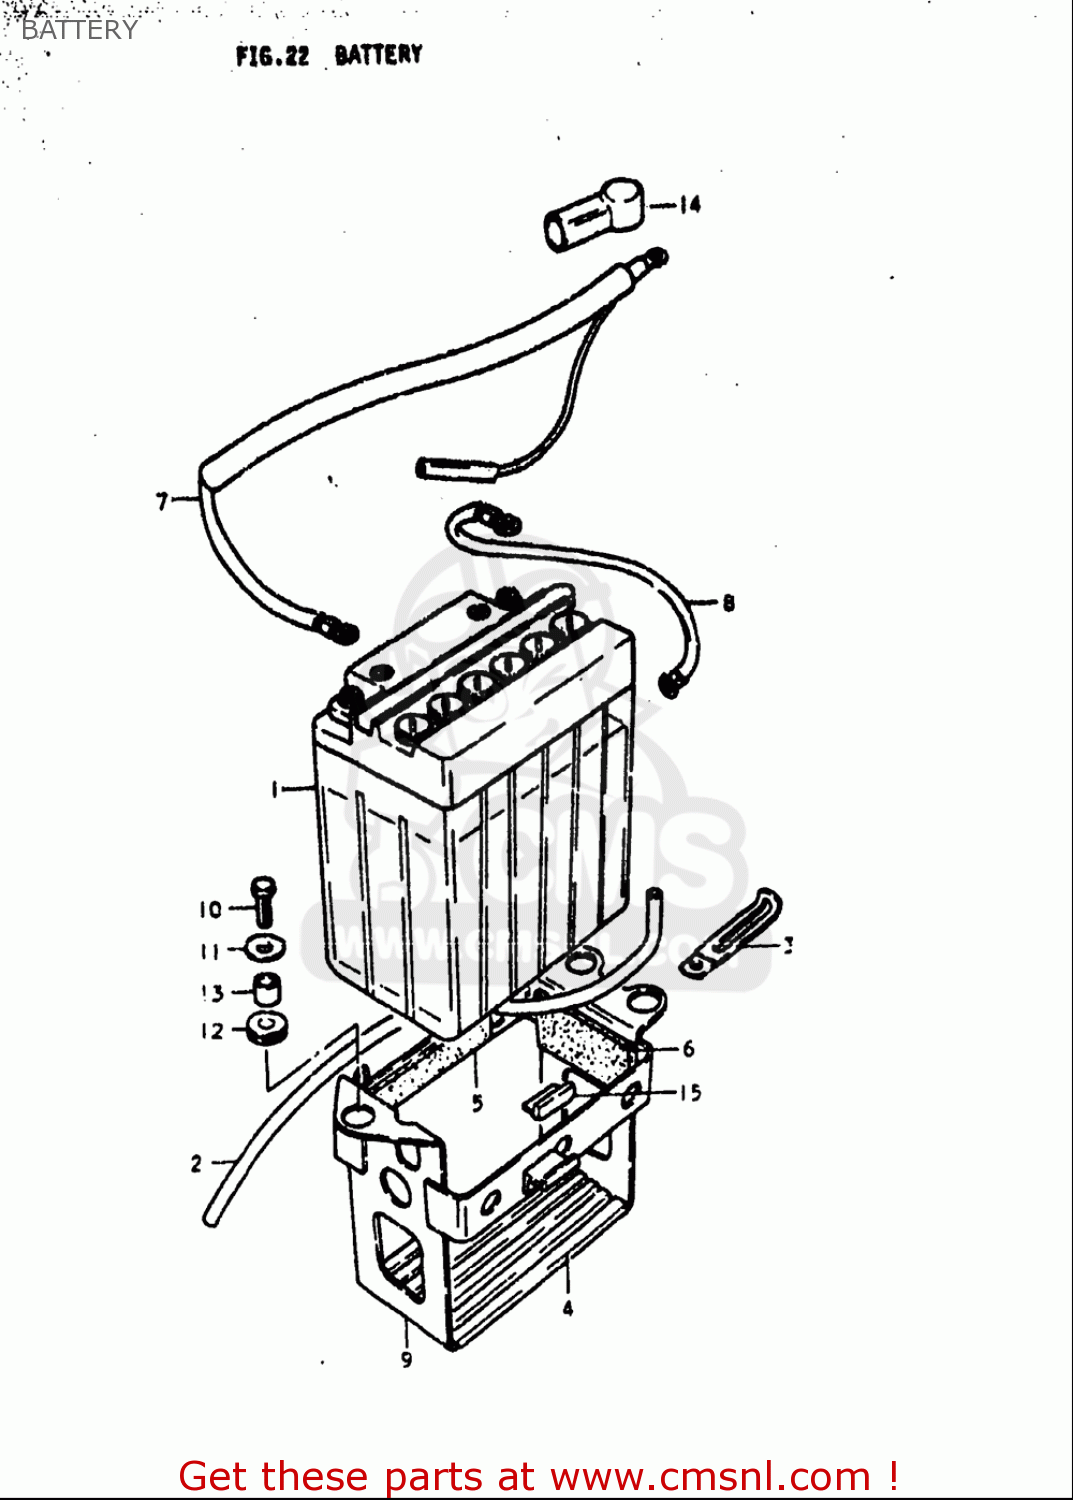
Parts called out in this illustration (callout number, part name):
1	BATTERY ASSY (12V)
2	HOSE,BATTERY EXHAUST
3	CLAMP(L:65)
4	PROTECTOR,BATTERY
5	PROTECTOR(170X95X3.0)
6	PROTECTOR(170X95X3.0)
7	WIRE,BATTERY PLUS
8	LEAD WIRE,BATTERY(-)
10	BOLT
11	WASHER(6.5X20X1.6)
12	CUSHION
13	SPACER(6.1X9X7.5)
14	CAP,TERMINAL
15	CUSHION,FRAME COVER
